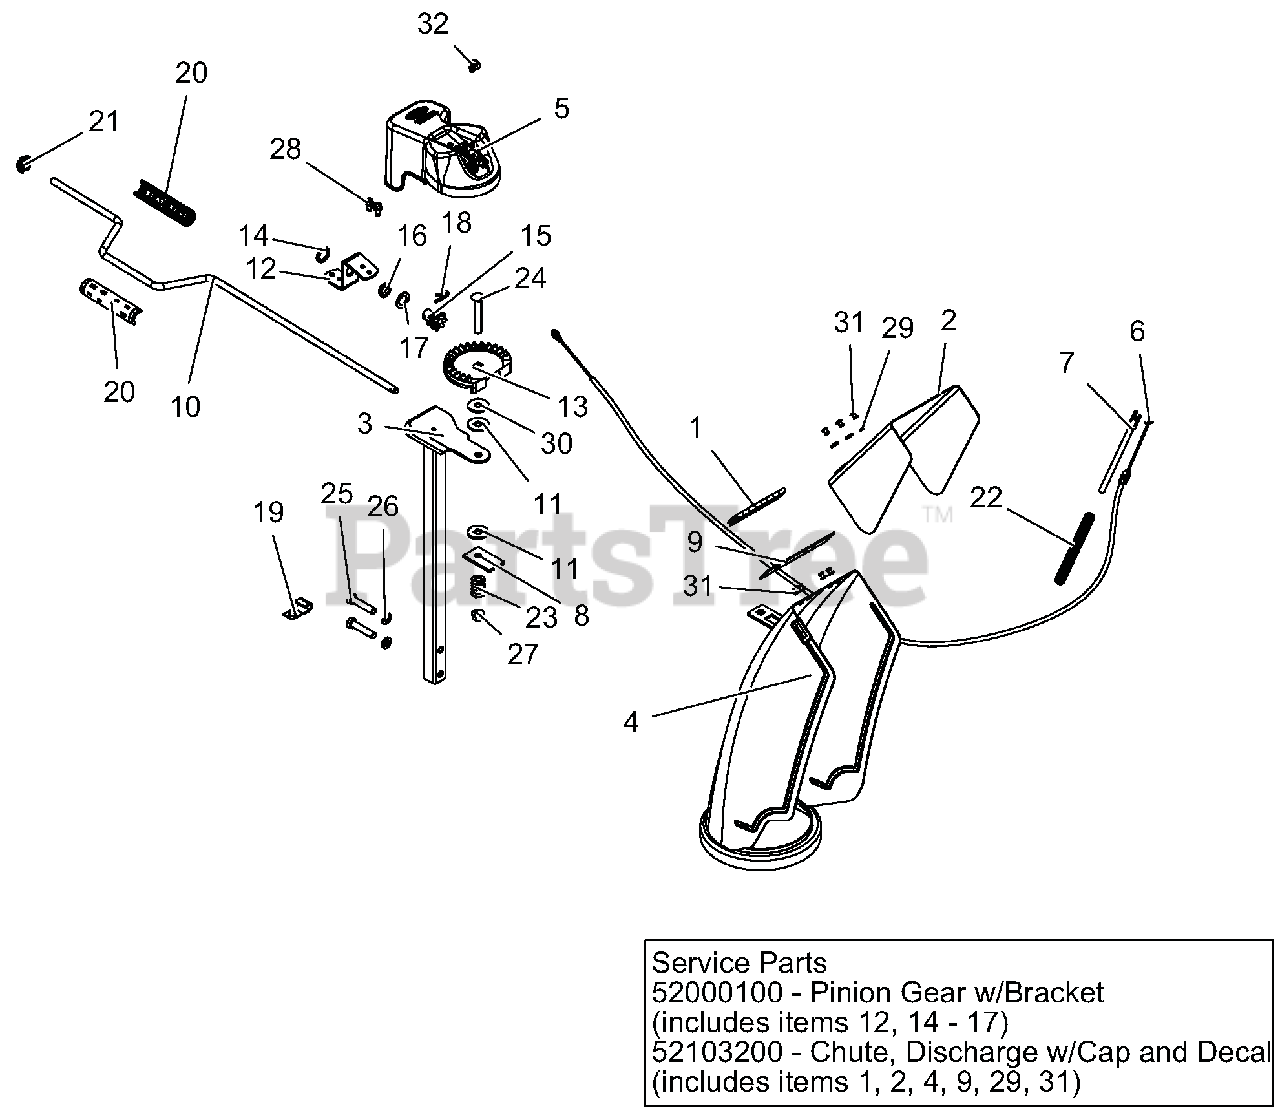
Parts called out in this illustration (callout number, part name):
2	CAP, LARGE
3	PEDESTAL, CHUTE - CRANK
4	WELDMENT, DISCHARGE CHUTE
5	DELUXE COVER W/SHEAR BOLTS KIT
6	CABLE, DEFLECTOR-COATED
7	ROD, DEFLECTOR CAP
8	PLATE, FRICTION
9	CAP SEAL 5.50
10	ROD, CHUTE CRANK
11	FRICTION WASHER
12	BRACKET, PINION GEAR
13	CHUTE GEAR
14	PUSHNUT .625
15	PINION GEAR - CHUTE
16	BUSHING, POLYLINER-.63 SNAPIN
17	WSHR-THRST .625 X 1.0 X .03
18	PIN, SPRING CLIP
19	J-CLAMP
20	KNOB, CRANK-SNAP
21	CRANK BUSHING, NYLON CHUTE BK
22	SG-COMP .08X.40X6.50 14#/IN
23	SG-COMP .187X.56X1.62
24	@BLT-RDHDSQNK .38-16X2.50 G5YZ
25	@BLT-HEX .38-16X1.75 GR5 YWZC
26	@WSHR-LK .38X.094 REG YWZC
27	@NUT-LK-TOP-FLG .38-16 YWZC
28	SCR-TAP .25-20X.50 HWH TR YWZ
29	WSHR-FL-STL .196X.500X.06 YZ
30	@WSHR-FL-STL .406X1.25X.10 ZC
31	RVT-POP .187 YZ
32	SCR-TAP .25-20X.50 LGHWH TR YZ
